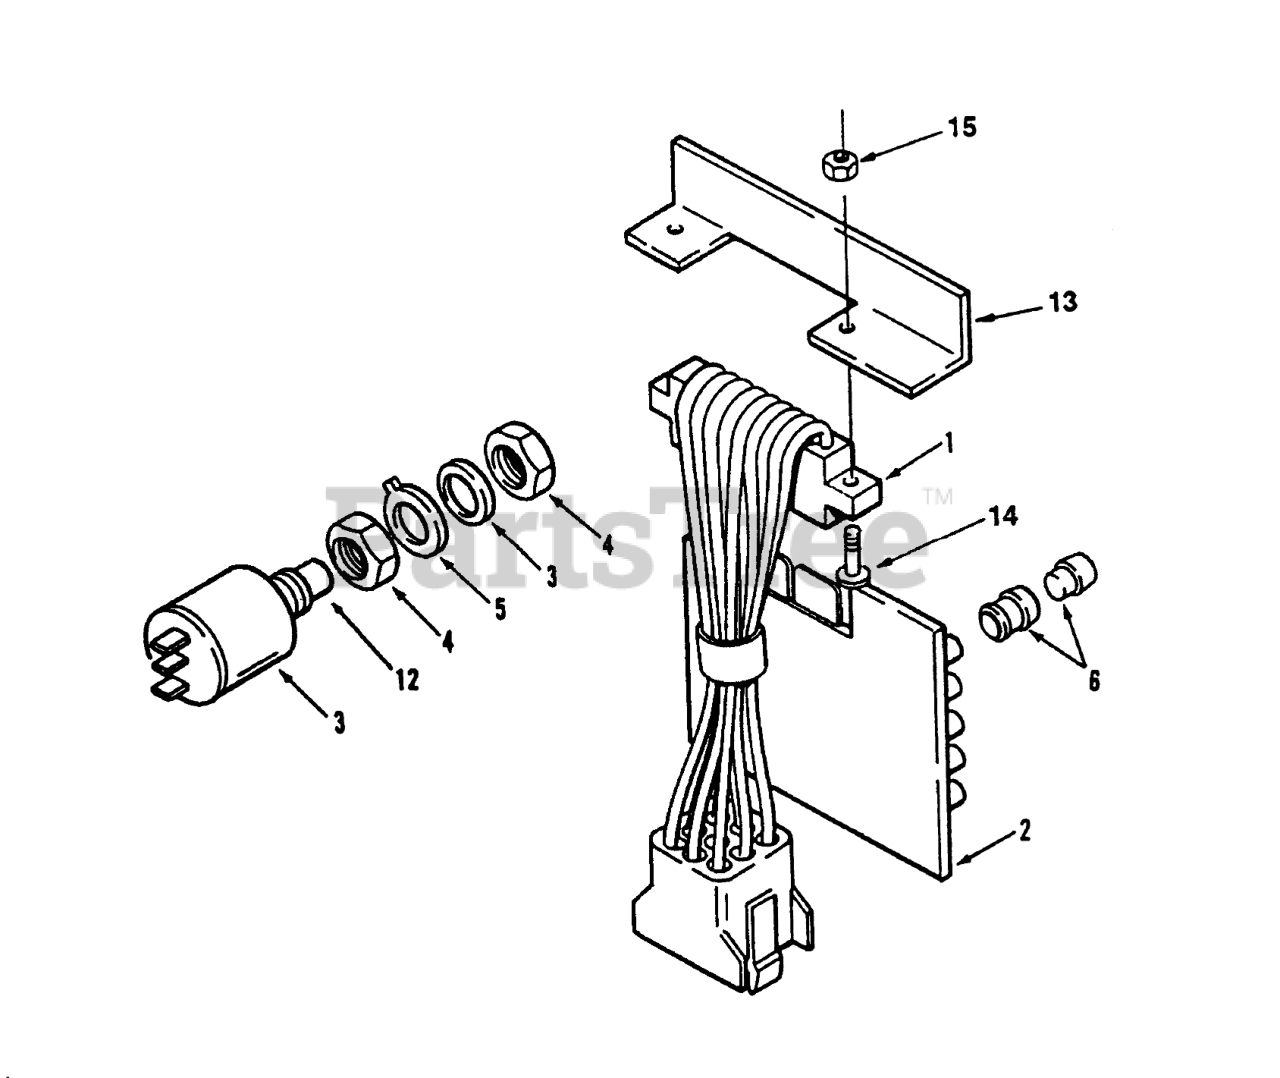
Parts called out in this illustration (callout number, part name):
1	P.C. BOARD HARNESS
2	Board-Pc
3	SWITCH-PUSH BUTTON
4	NUT F/W 116796
5	Washer
6	ASSY LENS & BUSHING
12	BUTTON F/W 116796
13	BRACKET
14	Screw #4-40 x 1/2
15	NUT HEX 4-40 ELAST
